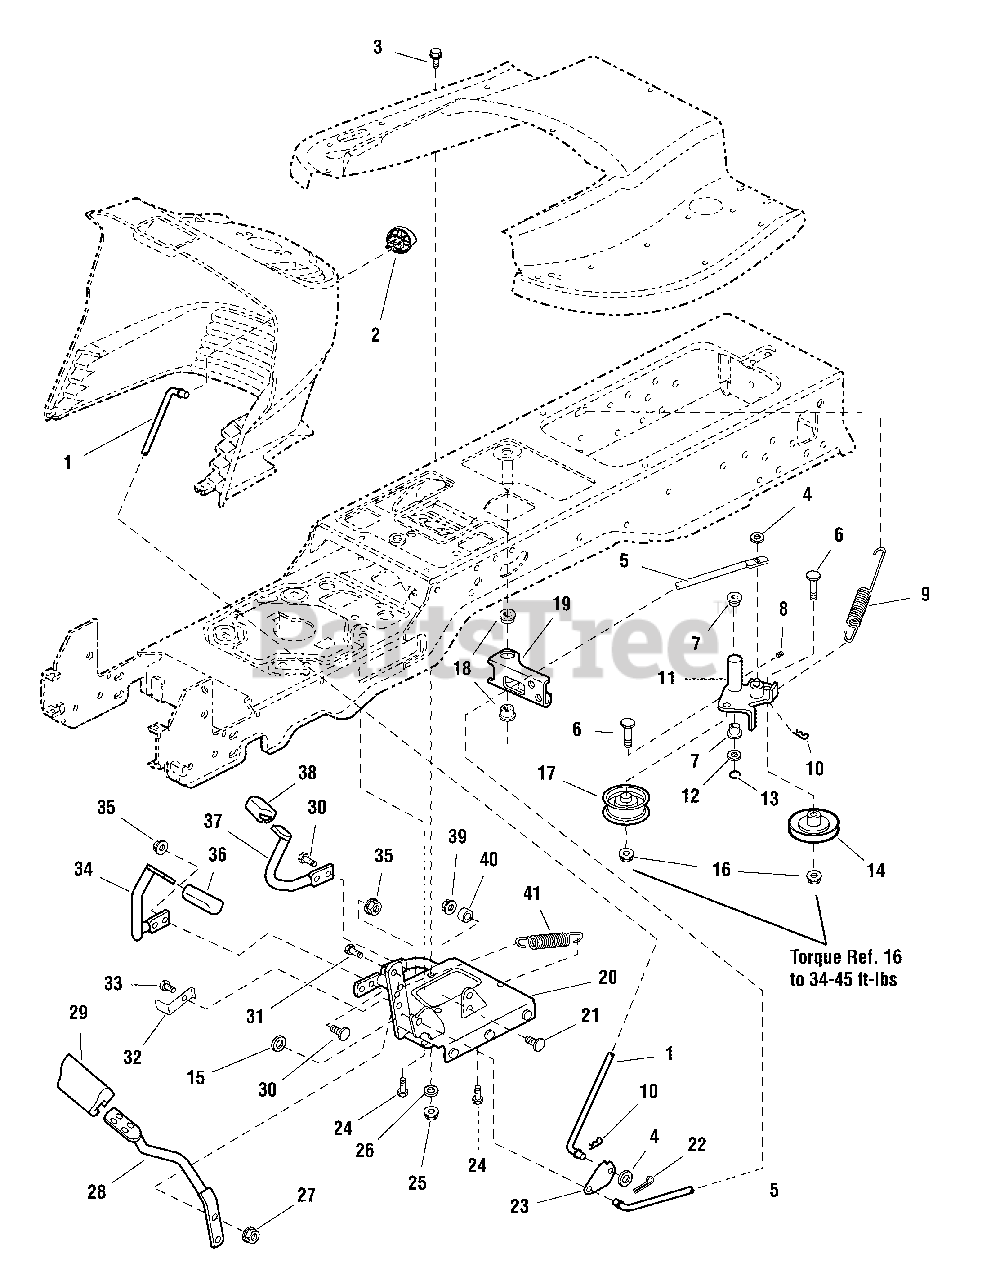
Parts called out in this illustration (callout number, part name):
1	ROD, Brake Lock
2	KNOB, Push On, Red Plastic "P"
3	CAPSCREW, Hex Flange Whiz Lock, 5/16-18 x 3/4
4	WASHER, 5/16, Black
6	BOLT, Carriage, 3/8-16 x 1 3/4
7	BUSHING, 5/8 x 3/4 x 3/4, Nylon
8	FITTING, Lube, 1/4
9	SPRING, Extension
10	PIN, Quick
11	ARM & HUB ASSEMBLY, Idler
12	WASHER, 5/8
13	RING, Clipring Extension
14	PULLEY, w/Bearing
15	WASHER, 3/8
16	NUT, Hex Flange ESNA, 3/8-16
17	PULLEY, Idler
18	BUSHING, 1 x 1-1/8 x 5/8, Nylon
20	PEDAL ASSEMBLY, Foot
21	BOLT, Carriage, 1/4-20 x 1-1/4
22	PIN, Cotter, Black
23	LATCH, Brake
24	CAPSCREW, Hex Washer Head Taptite, 5/16-18 x 3/4
25	NUT, Hex Lock ESNA Light, 5/16-18
26	WASHER, 5/16, Black
27	NUT, Hex Flange Whiz Lock Large, 5/16-18
28	PEDAL, Brake
29	PAD, Brake Pedal
30	BOLT, Carriage, 5/16-18 x 7/8
31	CAPSCREW, 5/16-18 x 1
32	ACTUATOR, Switch 2.53" Long
33	CAPSCREW, Hex Washer Head Taptite, 3/8-16 x 3/4
34	PEDAL, Forward
35	NUT, Hex KEPS, 5/16-18
36	PAD, Foot Pedal Forward
37	PEDAL, Reverse
38	PAD, Foot Pedal Reverse
39	NUT, Hex Lock ESNA Light, 1/4-20
40	CAM, Roller
41	SPRING, Extension
